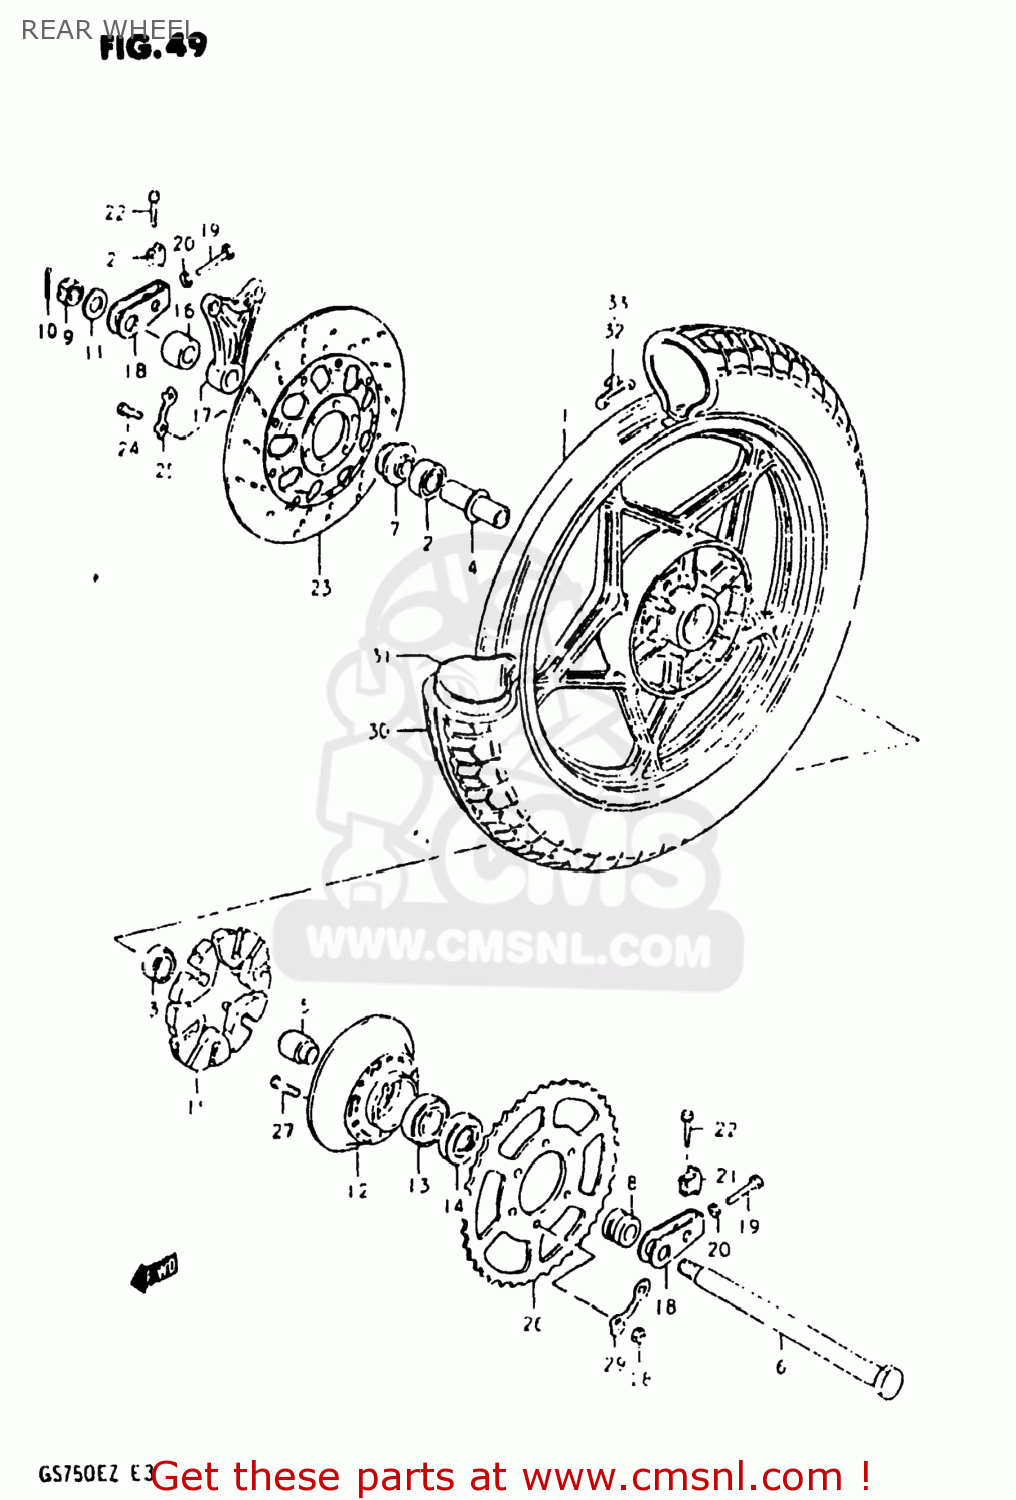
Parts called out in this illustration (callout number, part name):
1	CASTING WHEEL,REAR 2.15
2	BEARING WHEEL REAR(20X47X14)
3	BEARING, LH
4	SPACER,REAR HUB BEARING
5	SPACER,REAR HUB BEARING
6	AXLE,REAR
7	SPACER,REAR AXLE
8	SPACER(20X33X28.3)
9	NUT 18MM
10	PIN,COTTER
11	WASHER(19X34X4)
12	DRUM,REAR SPROCKET MOUNT
13	BEARING
14	SEAL,OIL(33X62X7)
15	ABSORBER,REAR HUB SHOCK
16	SPACER (20X38X17)
17	BRACKET,RR,CALIPER
18	ADJUSTER,CHAIN
19	BOLT 8X50
20	NUT
21	SUPPORTER,CHAIN ADJUST
22	BOLT (8X40)
23	DISC,RR BRAKE
24	BOLT(8X30)
25	WASHER
26	SPROCKET,RR
27	BOLT
28	NUT
29	WASHER
30	TIRE
31	TUBE,INNER
32	BALANCER,WHEEL
33	BALANCER,WHEEL
